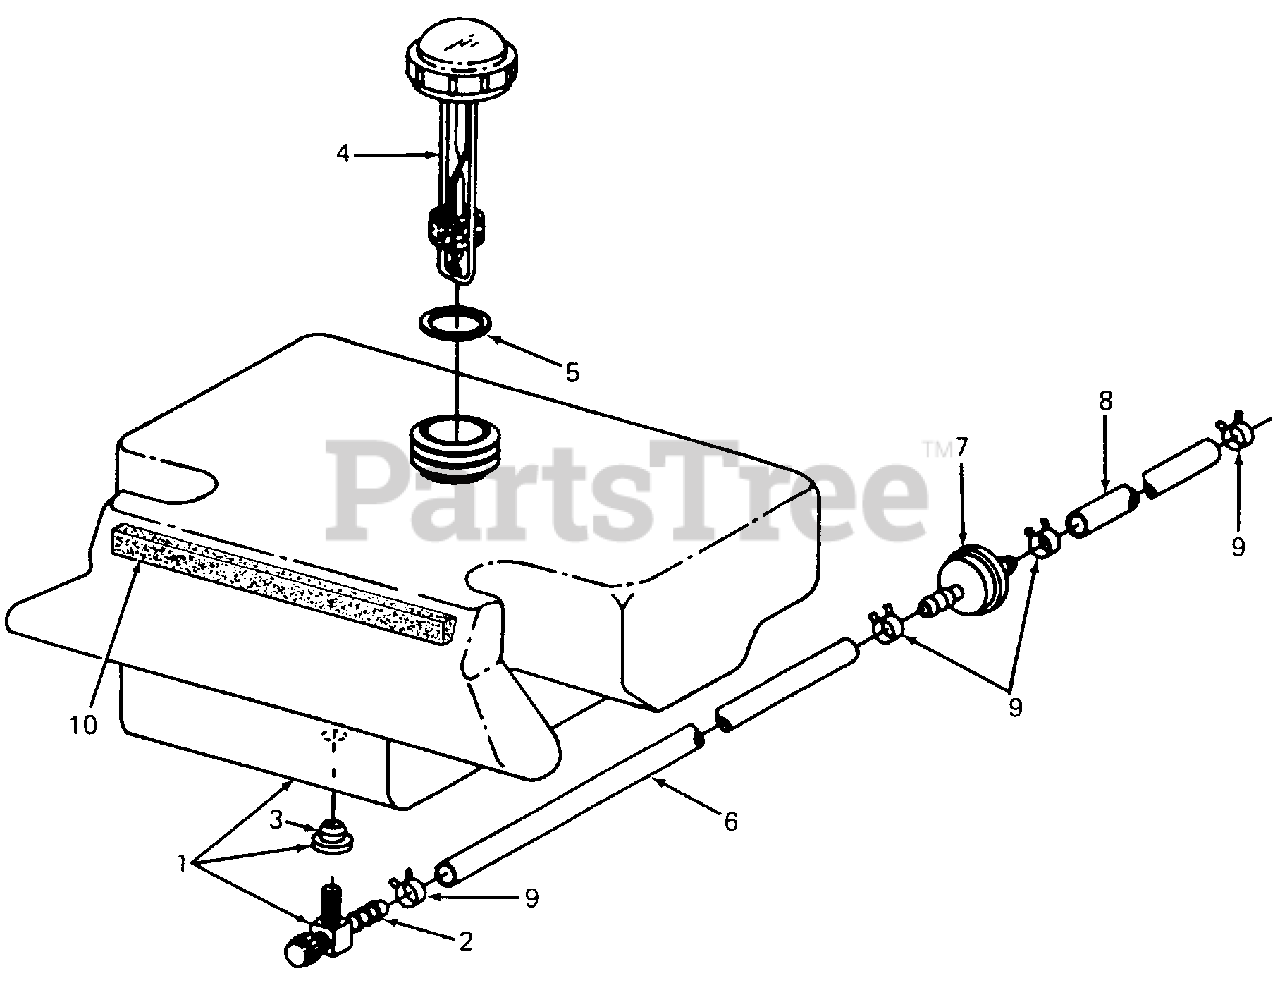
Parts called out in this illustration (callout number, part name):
1	Tank Assy, Fuel
2	Valve w/Screen, Shut-off
3	Bushing
4	Cap w/Gauge, Fuel
5	Gasket, Fuel Tank Cap
6	Line, Fuel Tank to Filter, 56 in. Lg
7	Filter, Fuel
8	Line, Fuel Filter to Engine, 25 in. Lg
9	Clamp, Tube Hose, 1/2 OD
10	Strip, Foam Gasket Sealing, 12 in. Lg
